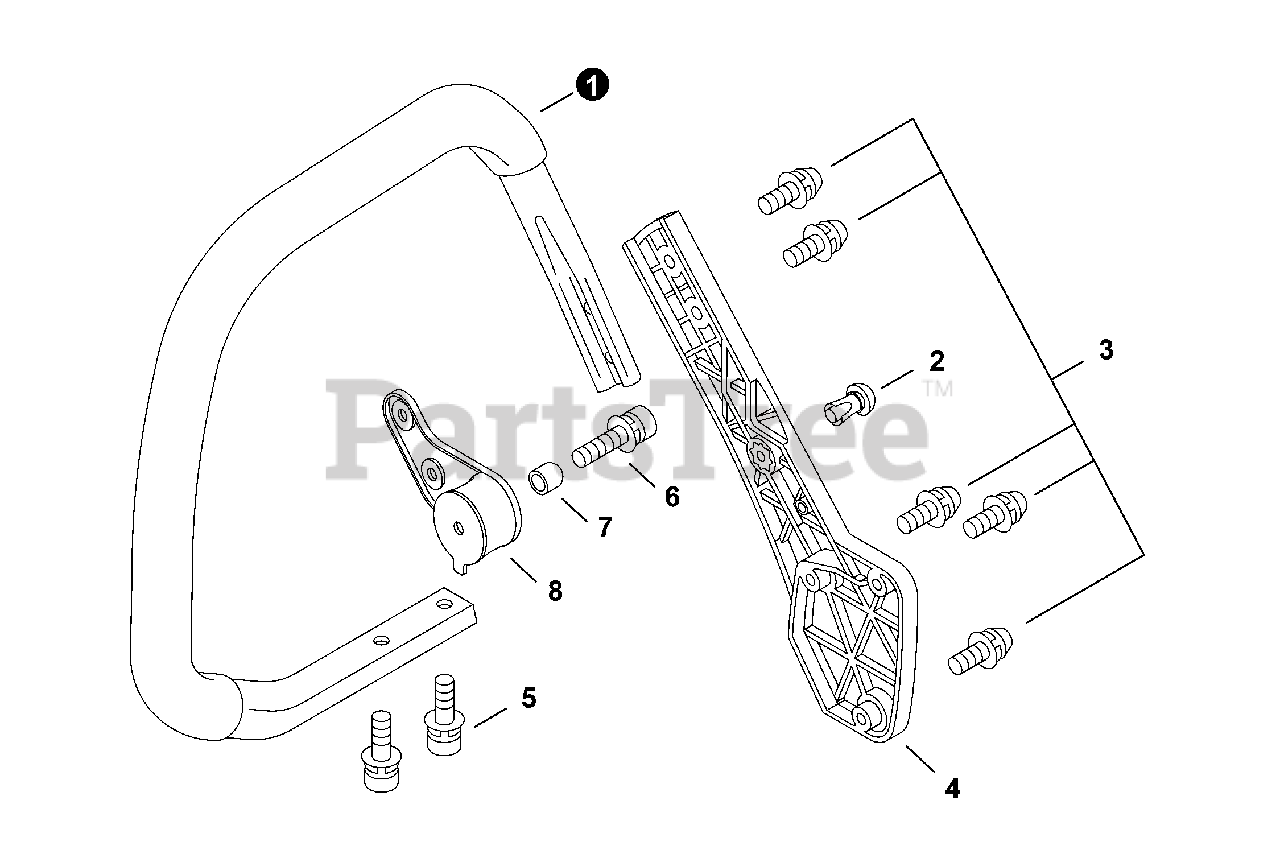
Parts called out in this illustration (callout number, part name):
1	HANDLE, FRONT
3	SCREW 5×20
4	BRACKET, HANDLE
5	BOLT 5×14
6	BOLT 5×20
7	COLLAR 5
8	CUSHION 5
